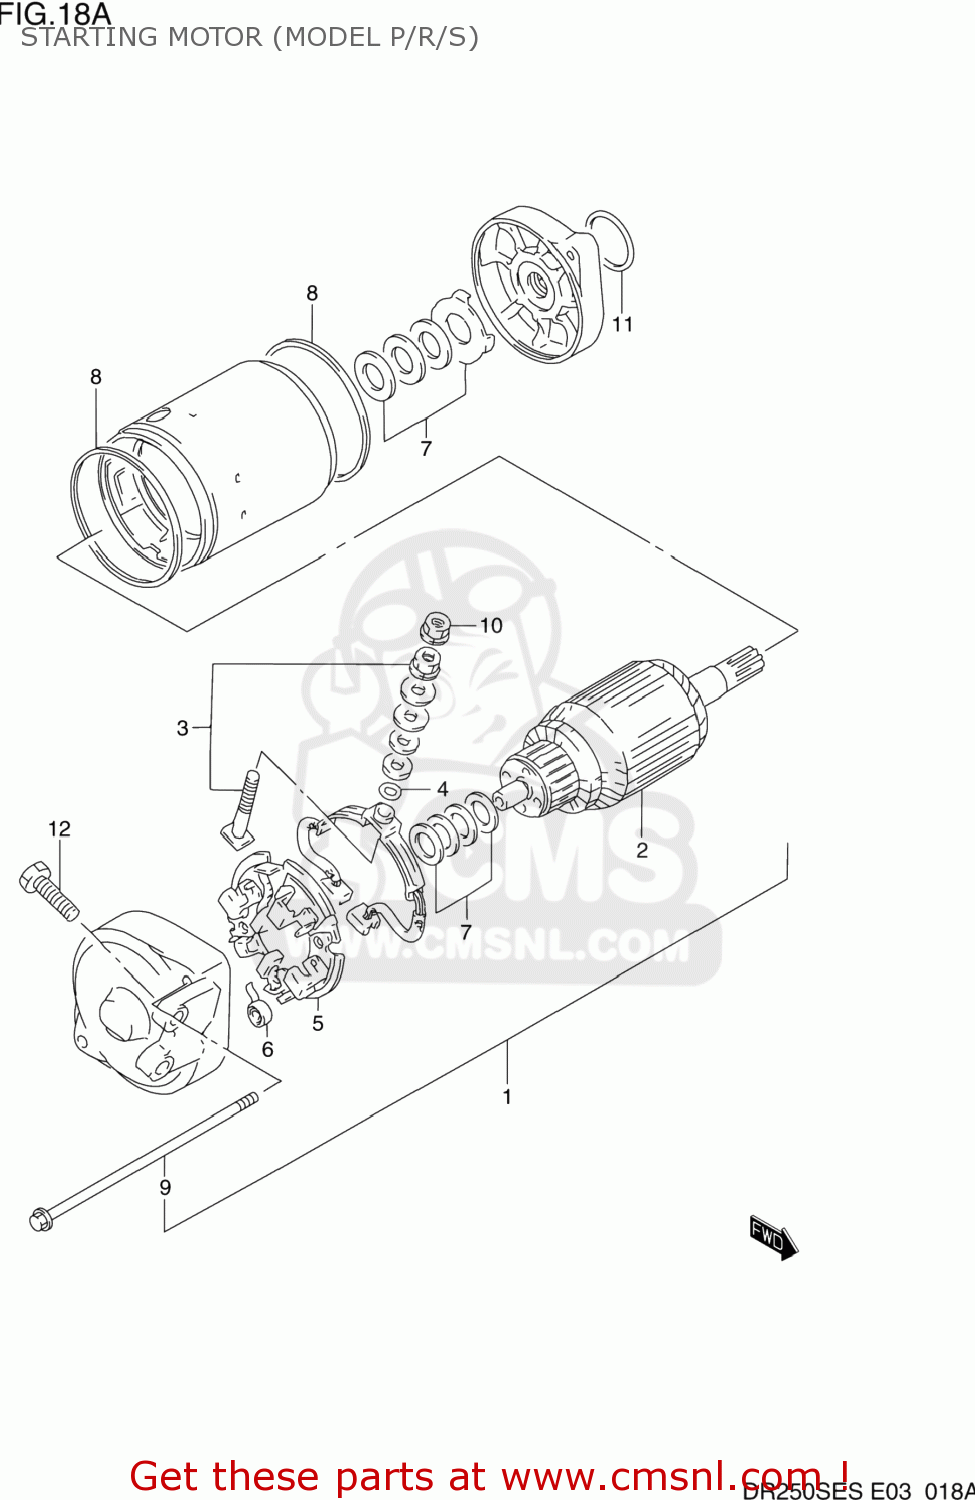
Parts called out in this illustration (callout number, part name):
1	MOTOR ASSY,STARTING
2	ARMATURE
3	TERMINAL SET,BRUSH
4	O RING
5	HOLDER SET,BRUSH
6	SPRING,BRUSH
7	SHIM SET,STARTING MOTOR
8	O RING
9	BOLT
10	NUT
11	O RING(D:3,ID:24.5)
12	BOLT
